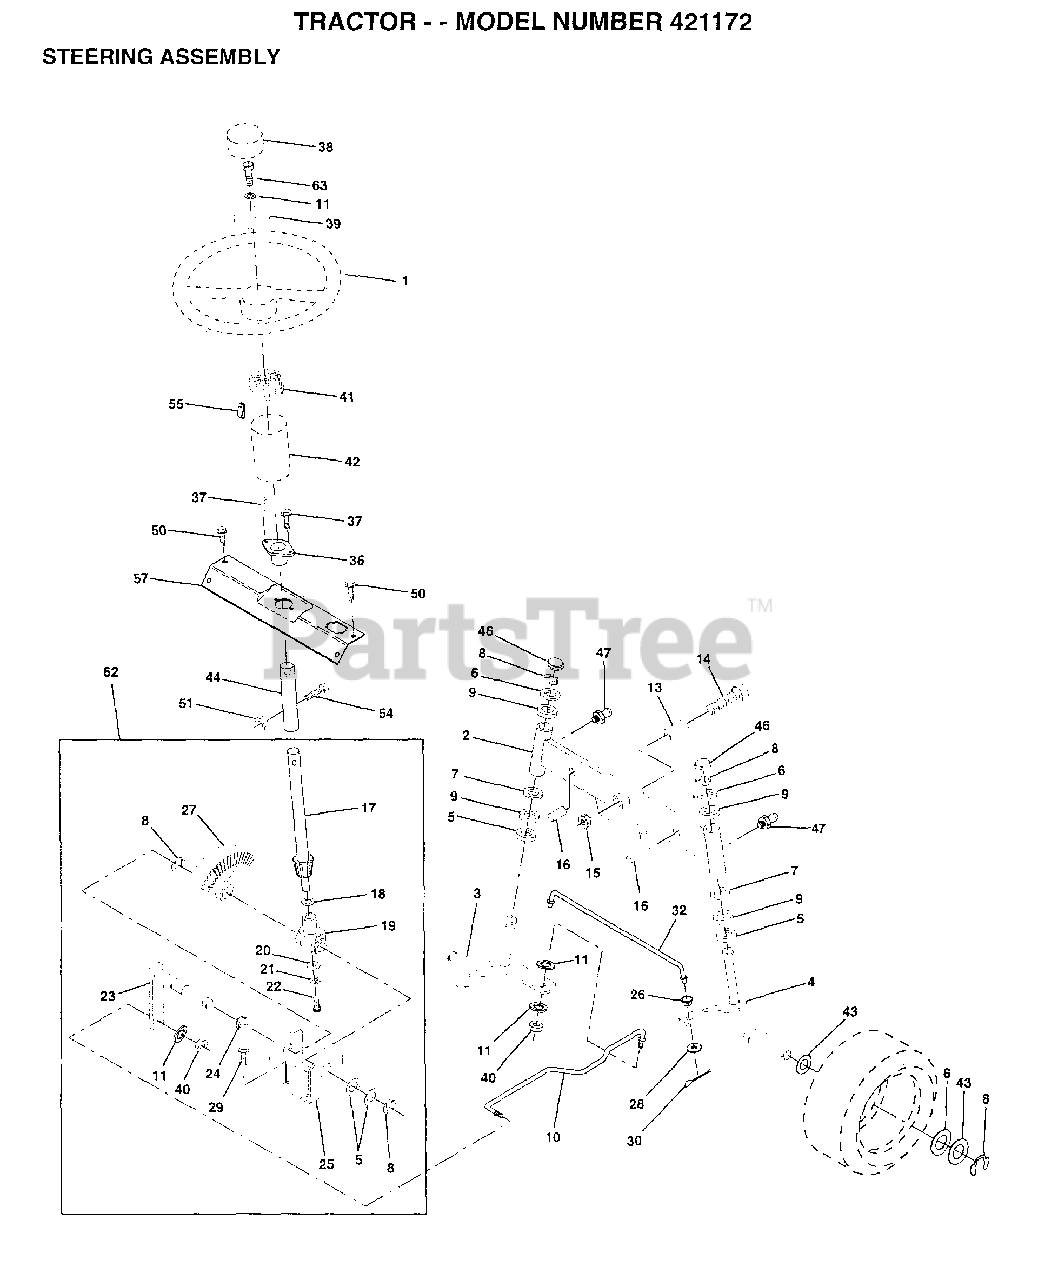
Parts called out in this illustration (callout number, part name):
2	AXLE ASM FRONT
3	SPINDLE LH
4	SPINDLE RH
5	WASHER .T
6	WASHER
7	WASHER
8	RING
9	COL. SRTG. BEAR.
11	LOCKWASHER
13	BEARING
14	BOLT HEX 5/8-11
15	"NUT-LOC,FLANGE LT"
16	AXLE PIN
17	SHAFT ASM STEERIN
18	THRUST WASHER
19	SUPPORT.SHAFT
21	LOCKWASHER
22	SCREW.SCKTHD.CAP
24	NYLINER T
25	"BRKT,STEERING"
26	BUSHING.DRAGLINK
27	GEAR SECTOR
28	WASHER
29	SCREW
30	COTTER PIN
32	TIE ROD
37	"SCREW-TT,10-32 FL"
38	ST WHL INSERT CAP
39	WASHER T
40	GRIPCO NUT
41	ADAPTER LT
42	BOOT SHAFT STEER
43	WASHER
44	SHAFT EXT STEERIN
46	CAP
47	ZERK M
50	SCREW HEX CRT
52	NUT
54	BOLT
55	CLIP TINNERMAN
57	SUPPORT SHAFT STR
63	BOLT
